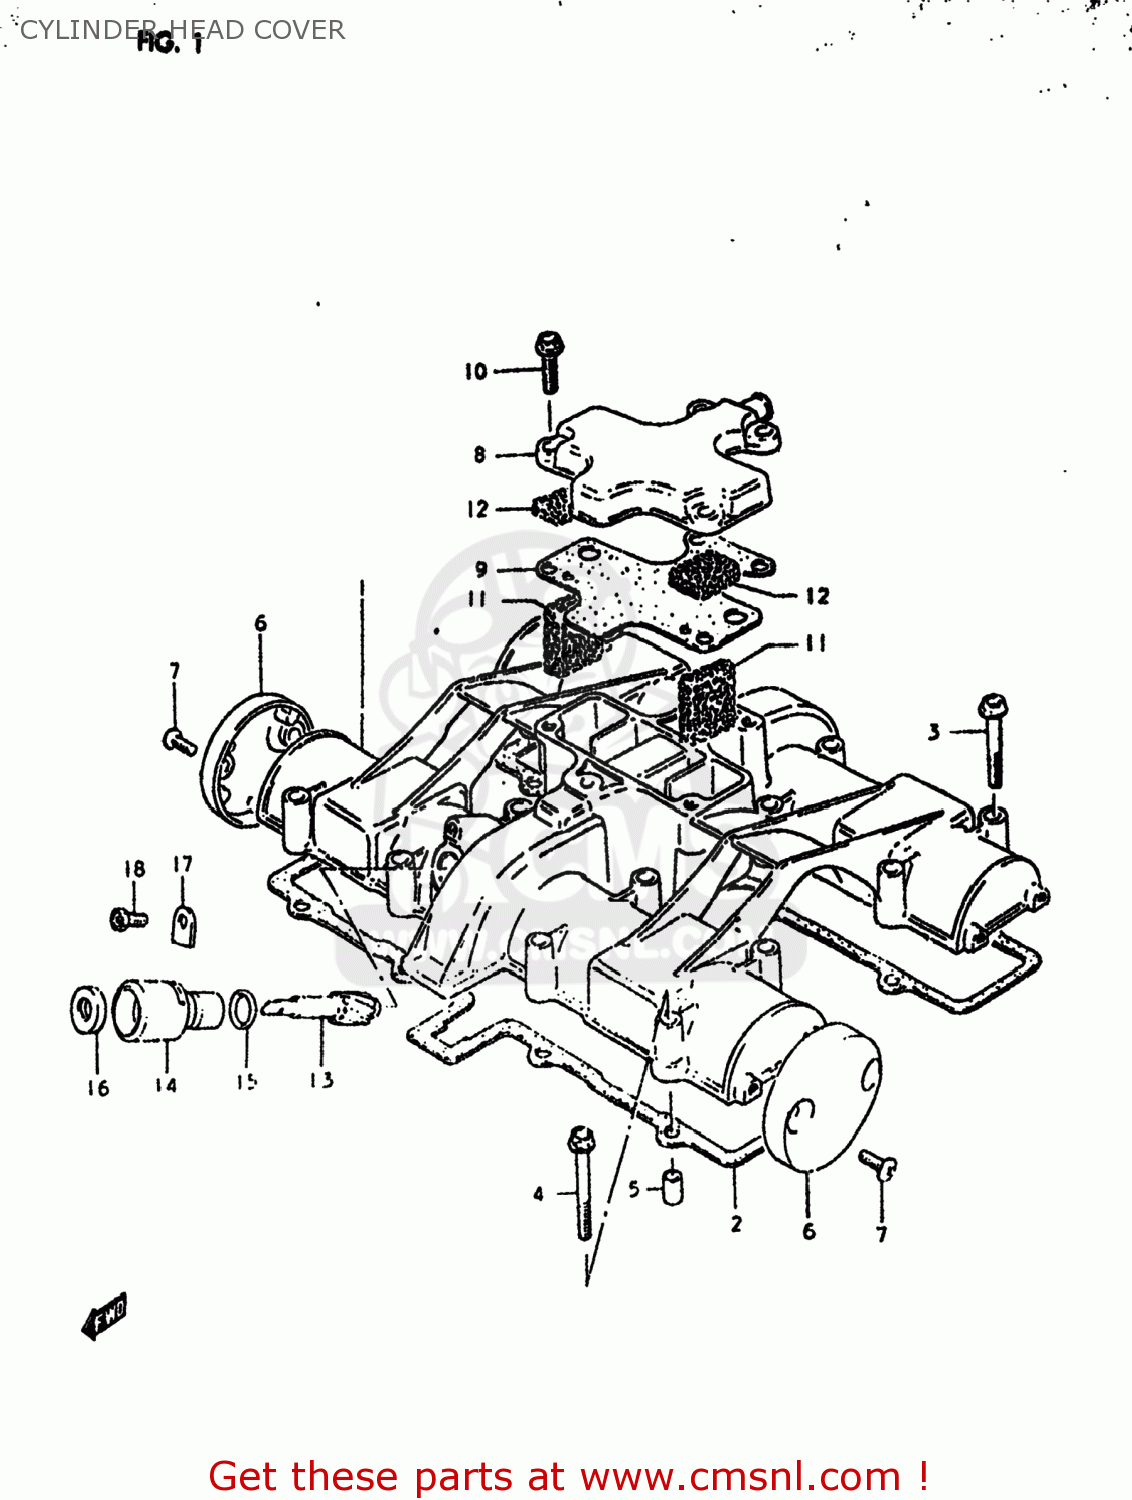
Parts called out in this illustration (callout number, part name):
1	COVER,CYLINDER HEAD
2	GASKET,CYLINDER HEAD COVER (MCA)
3	BOLT
4	BOLT,UNDER
5	PIN(6.2X8X11)
6	CAP,CYLINDER HEAD COVER
7	SCREW
8	COVER,BREATHER
9	GASKET (MCA)
10	BOLT,REAR
11	COVER,BREATHER
12	SEPARATOR,OIL BREATHER
13	GEAR,TACHOMETER DRIVEN
14	SLEEVE,TACHOMETER DRIVE
15	SEAL,TACHOMETER DRIVEN
16	SEAL,OIL(5X12X8)
17	PLATE,TACH DRIVE GEAR SLEEVE
18	SCREW(5X12)
